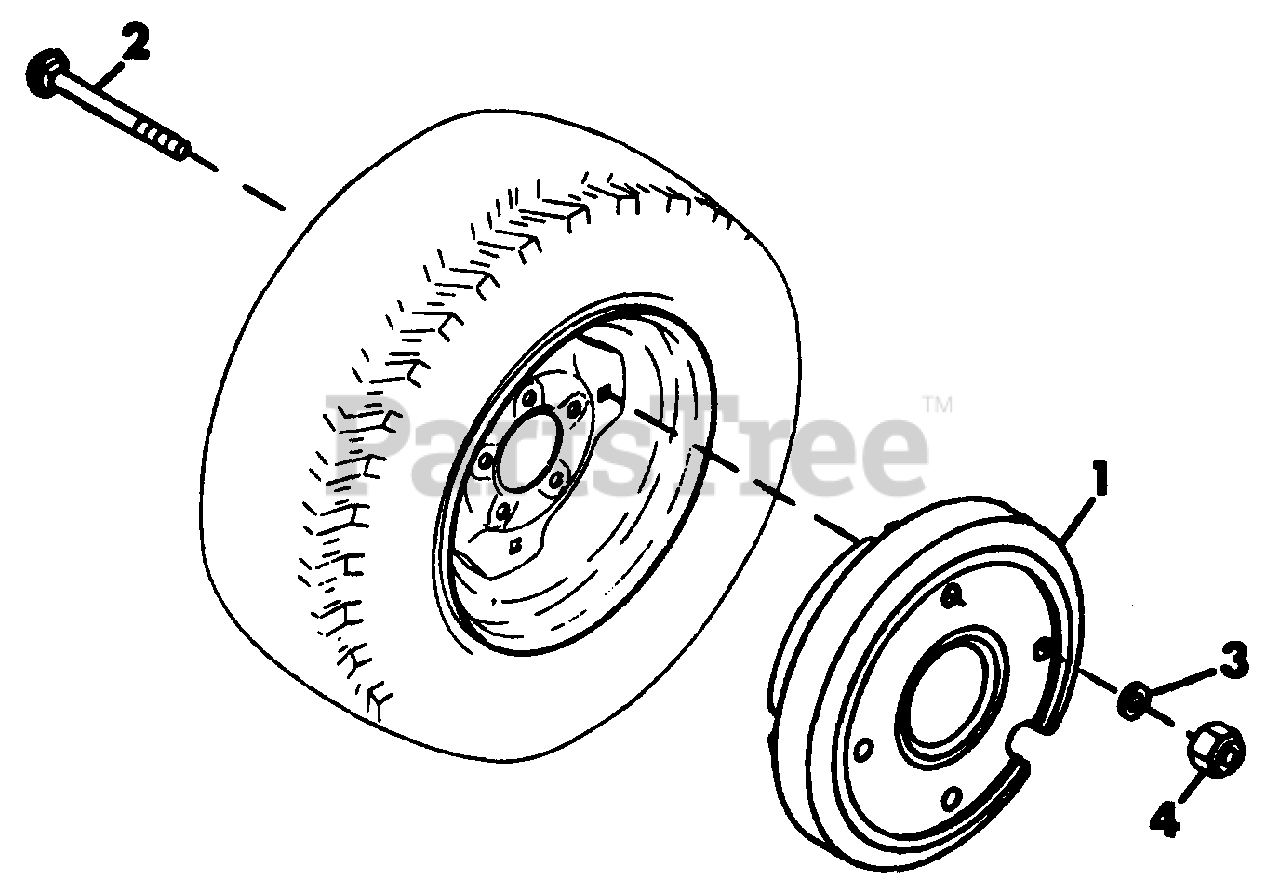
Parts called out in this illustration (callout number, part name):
1	WEIGHT, REAR WHEEL
2	BOLT, 1/2-13X7.00 RD HD SQ NK
2	BOLT, 1/2-13X8.00 RD HD SQ NK
3	WASHER, FLAT .531X1.000X.063
4	NUT, LOCK 1/2-13
